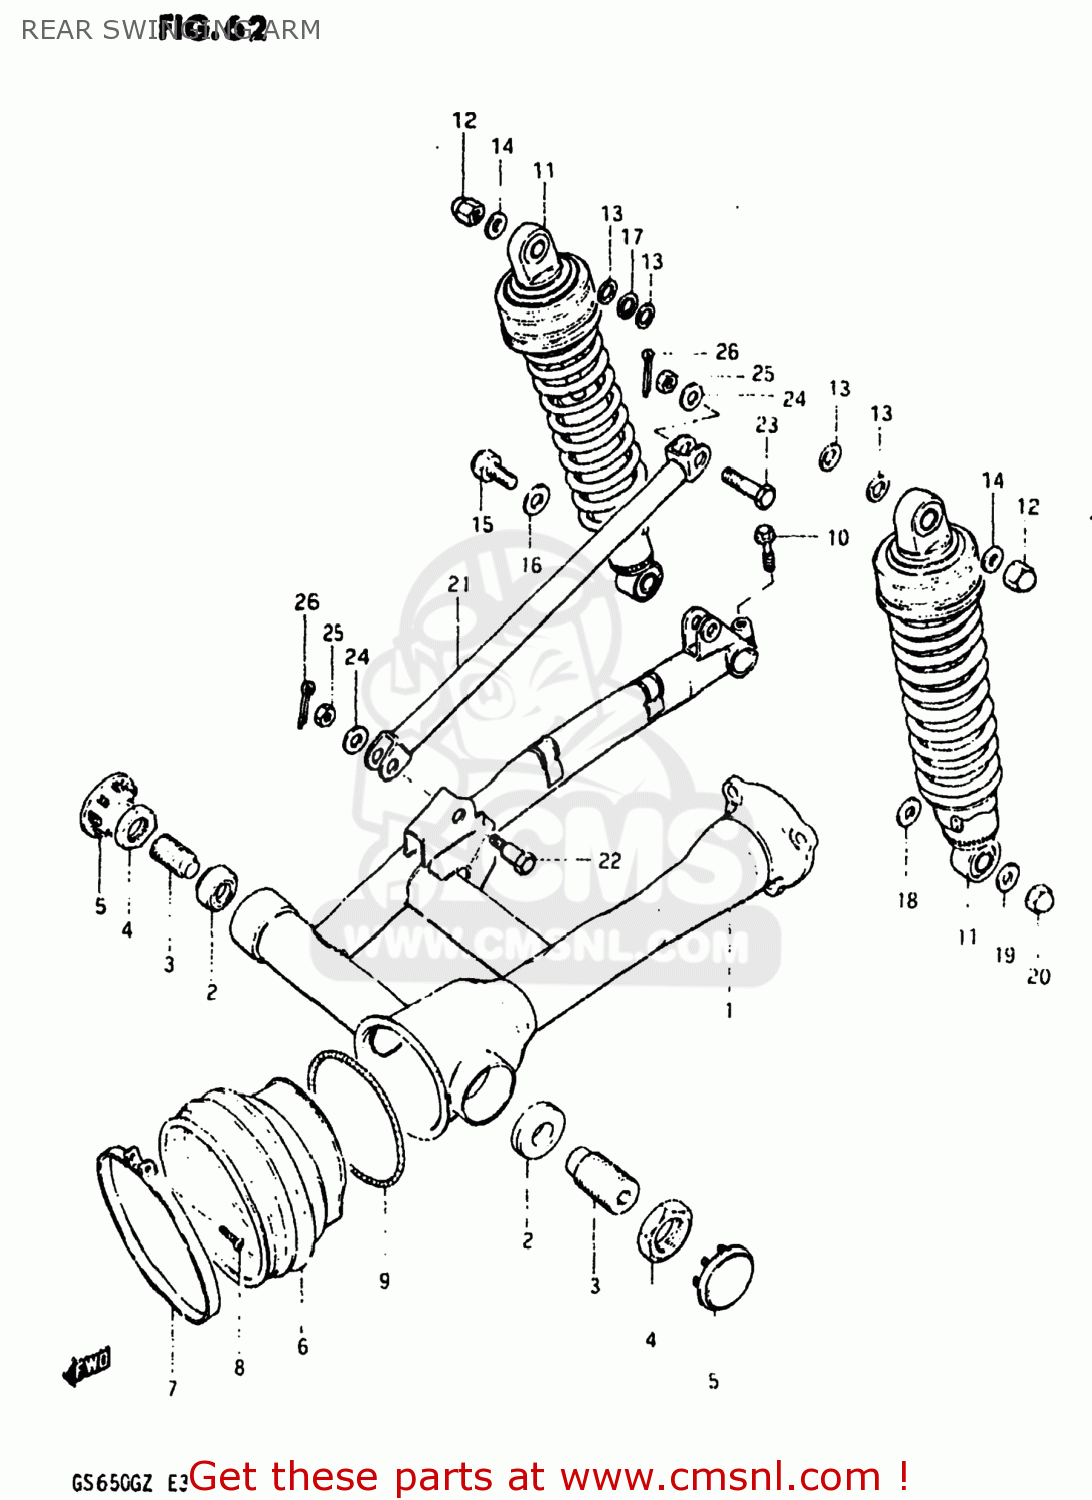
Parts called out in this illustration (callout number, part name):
1	SWING ARM ASSEMBLY,REAR
2	BEARING(15X35X11.75)
3	BOLT,REAR SWING ARM PIVOT
4	NUT (22MM)
5	CAP,REAR SWING ARM PIVOT
6	BOOT,PROPELLER SHAFT
7	CLAMP
8	SCREW 4X25
9	SPRING,PROPELLER SHAFT
10	BOLT
11	ABSORBER ASSEMBLY,REAR SHOCK
12	NUT
13	WASHER
14	WASHER
15	BOLT 12X33
16	WASHER (12.5X24X1.6)
17	WASHER (12.5X24X3.2)
18	WASHER
19	WASHER
20	NUT, LOWER LH
21	TORQUE LINK,REAR
22	BOLT
23	BOLT(10X39)
24	WASHER
25	NUT
26	PIN 20X20
